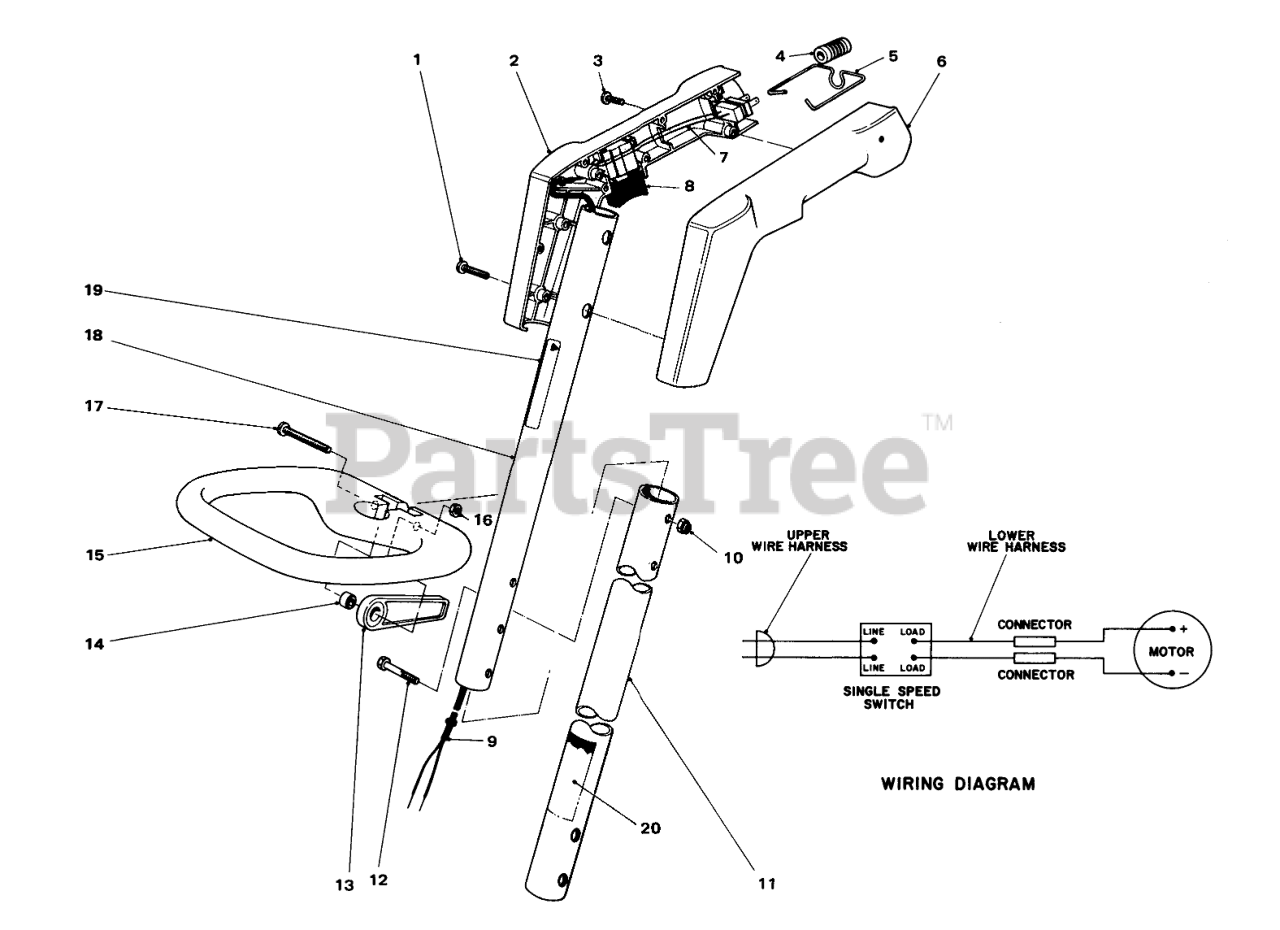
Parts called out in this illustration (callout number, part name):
2	Right Hand Grip
3	SCREW-PPH
4	RETAINER EXT. LORD
5	Extension Cord Wire Clamp
6	Left Hand Grip
7	WIRING HARNESS UPPER
8	SWITCH SINGLE SPEED
9	WIRING HARNESS STD
10	NUT-LOCK, NI
11	Lower Tubing
12	Screw
13	Cam Lock
14	Spacer
15	HANDLE ADJUSTABLE
16	NUT-HEX
17	Screw
18	Upper Tubing
19	Caution Decal
20	REPLACEMNT SERIAL PLT
